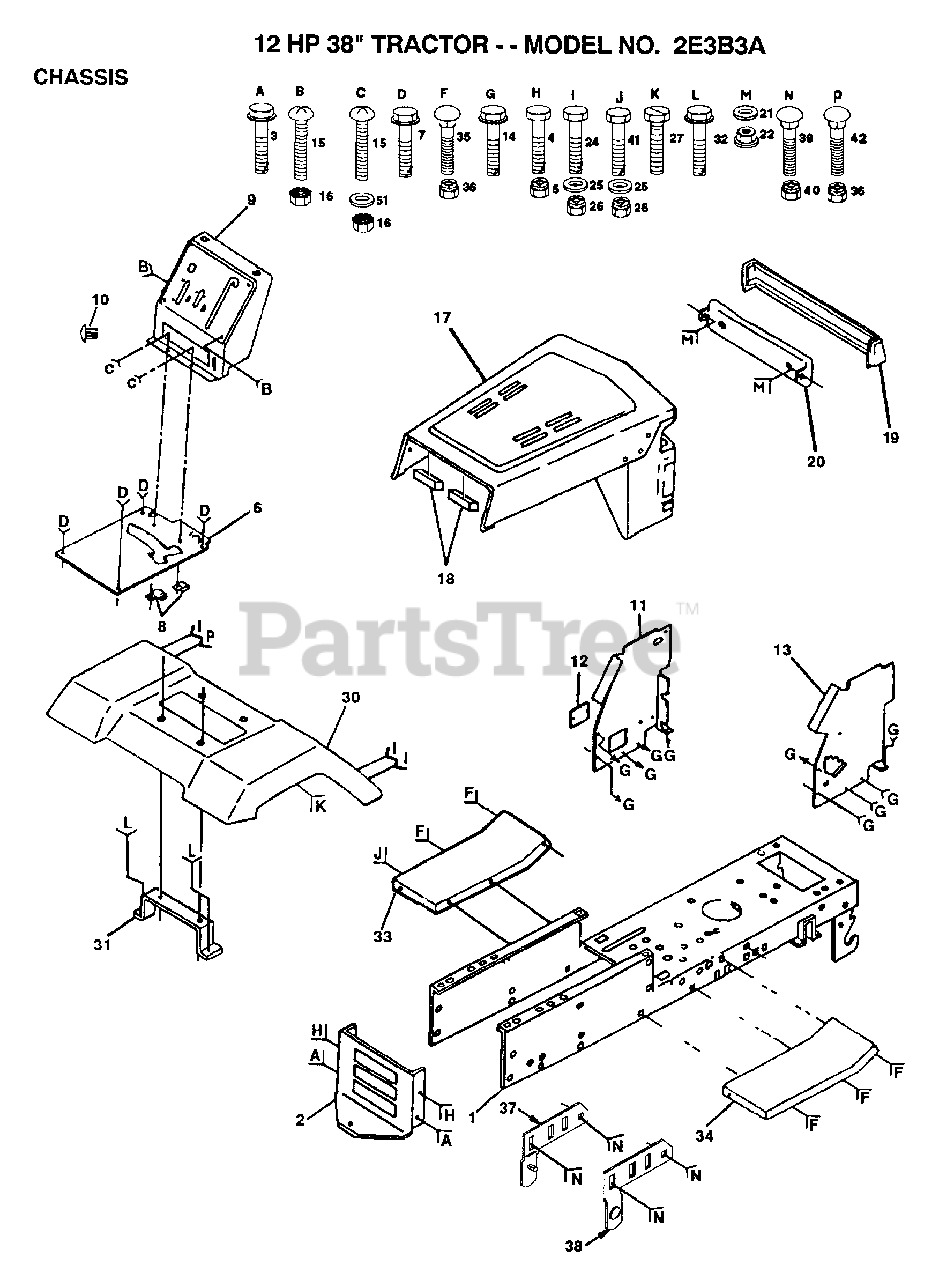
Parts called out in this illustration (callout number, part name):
2	DRAWBAR LT/YT
3	SCREW
7	SCREW LT
8	CLIP T
10	PLUG BUTTON T
11	PANEL DASH LH
12	COVER ACCESS
14	SCREW LT
15	SCREW
17	HOOD/GRILLE ASM SILKSCREEN WELDED
19	LENS SERVICE KIT
21	WASHER PM
22	PAL NUT LT
25	WASHER
27	SCREW LT
30	FENDER
31	BRKT FENDER
32	SCREW
33	FOOTREST LH
34	FOOTREST RH
35	BOLT
37	BRKT ASM PIVOT LH
38	BRKT ASM PIVOT RH
39	BOLT
40	NUT
51	WASHER
